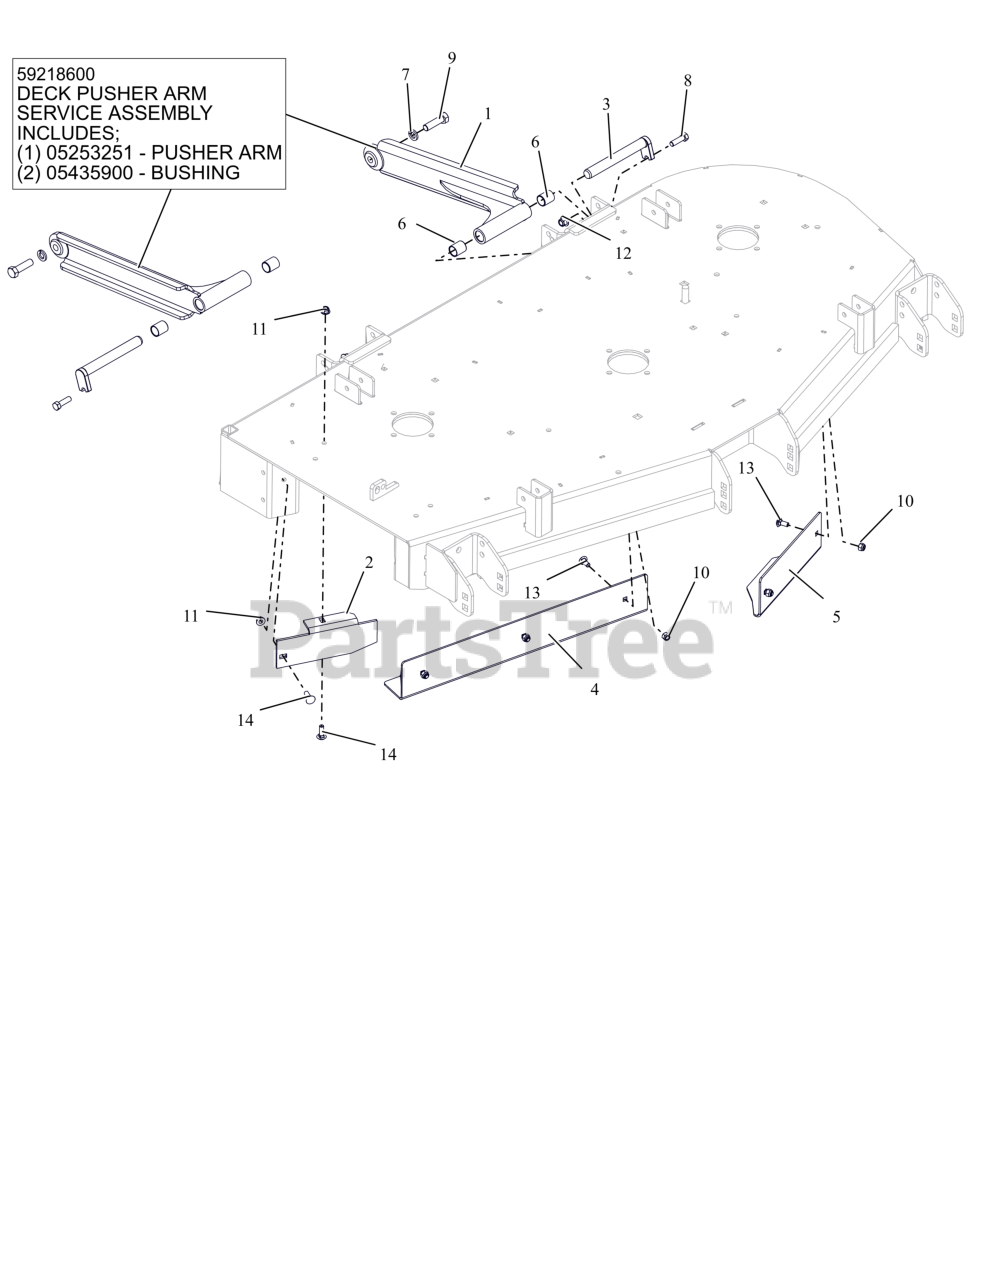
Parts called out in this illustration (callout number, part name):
1	WLDMT, DECK STABILIZER ARM (BLACK)
1	DECK STABILIZER ARM W/BUSHINGS
2	52" DISCHARGE BAFFLE - RED
3	PIN, MOWER MTG
4	BAFFLE, 52" RH VACUUM (RED)
5	BAFFLE, 52" LH VACUUM (RED)
6	BRG, .750 X .875 X 1.000
7	WSHR,LK-REG .500X.125 ZCC
8	BLT, HEX .38-16X1.25 G5 ZCC
9	BLT, HEX 0.5-13X1.75 GR5 ZCC EP80
10	NUT,NYL .31-18 G5 ZCC
11	NUT,NYL-FLG .31-18 GF ZCC
12	NUT,NYL-FLG .38-16 GF ZCC
13	BLT,RHSN .31-18X.75 G5 ZCC
14	BLT,RHSN .31-18X1.00 G5 ZCC
